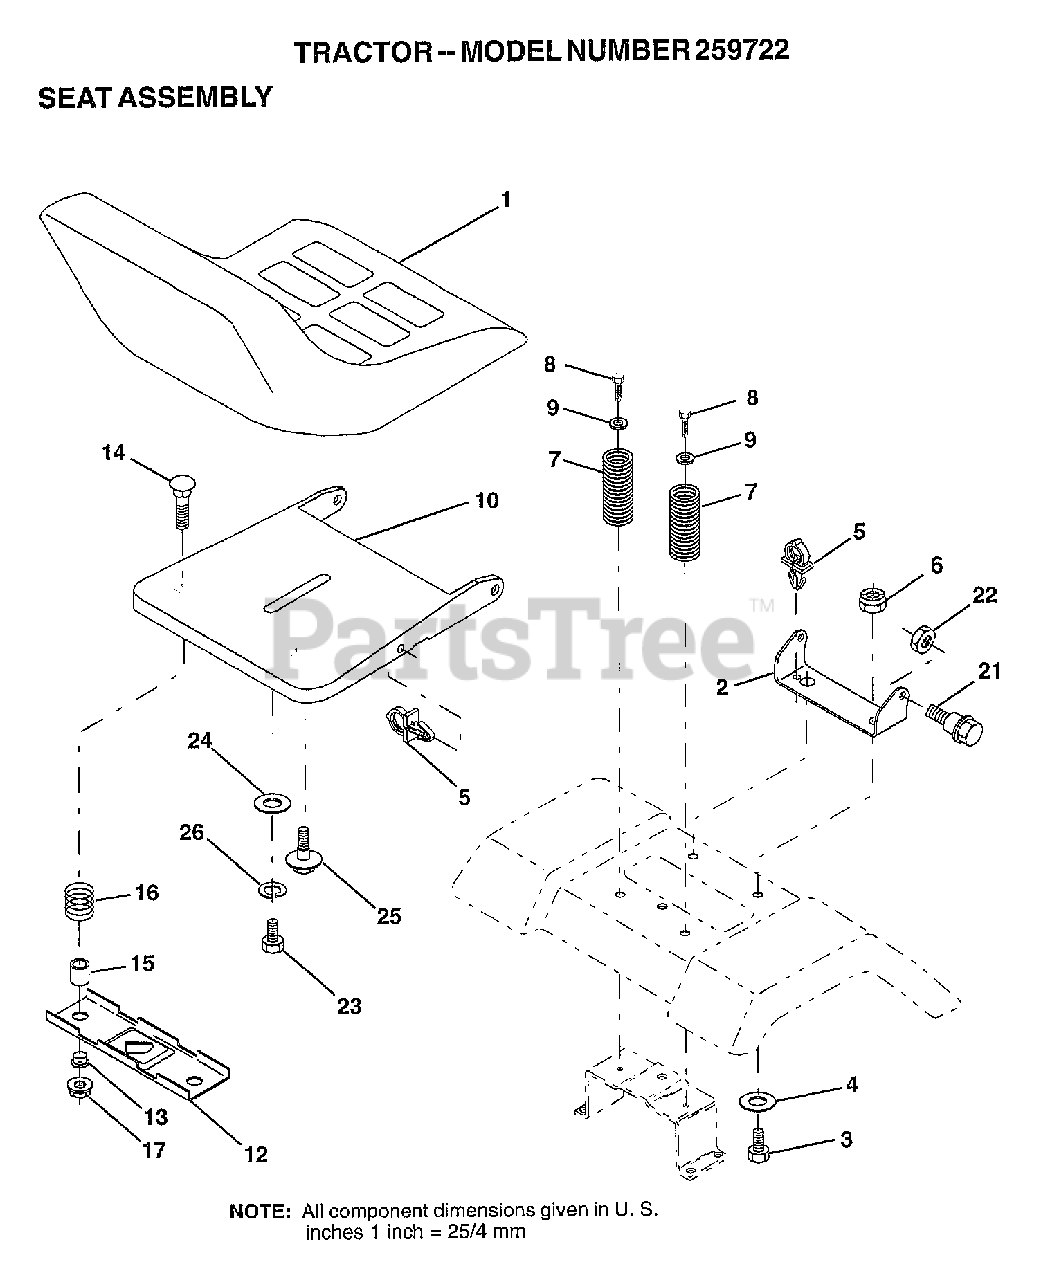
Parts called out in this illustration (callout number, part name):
2	BRACKET PVT SEAT
3	BOLT
4	WASHER PM
5	CLIP.PUSH-IN.HING
6	NUT
7	SPRING COMPRESSIO
8	SCREW
9	WASHER
10	PAN-SEAT
12	BRKT SWITCH
13	BUSHING
14	BOLT-RD HD SQ NK
15	SPLIT SPACER
16	SPRING
21	BOLT
22	NUT
23	BOLT
24	WASHER
26	LOCKWASHER
